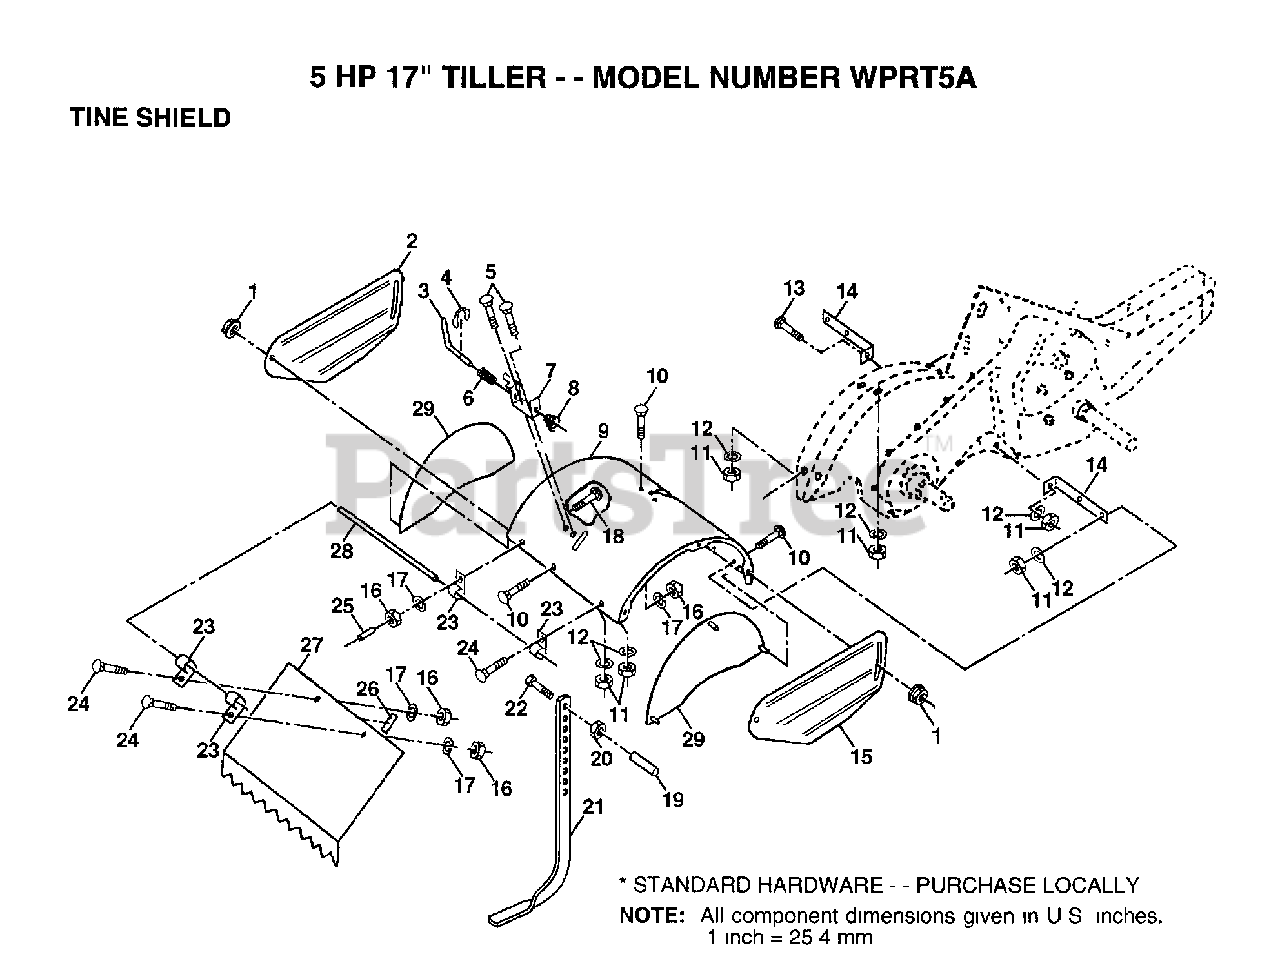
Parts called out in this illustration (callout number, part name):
1	NUT
2	SHIELD.SD.OUT.LH
3	STAKE PIN TI
4	KLIP RING TI
5	BOLT CRT
6	SPRING TI
7	LATCH BRACKET TI
8	SPRING CRT
9	"SHIELD, TINE"
10	BOLT
11	NUT.HEX.5/16-18
12	LOCKWASHER
13	BOLT
14	BRKT SHIELD TINE
15	SHIELD.SD.OUT.RH
17	LOCKWASHER
18	BOLT
19	GRIP CRT
20	NUT.HEX.3/8-16UNC
22	BOLT
23	HINGE CRT
24	BOLT
25	VINYL CAP TI
26	PAD IDLER TI
27	LEVELING SHIELD
28	PIN HINGE
29	"SHIELD, SIDE"
